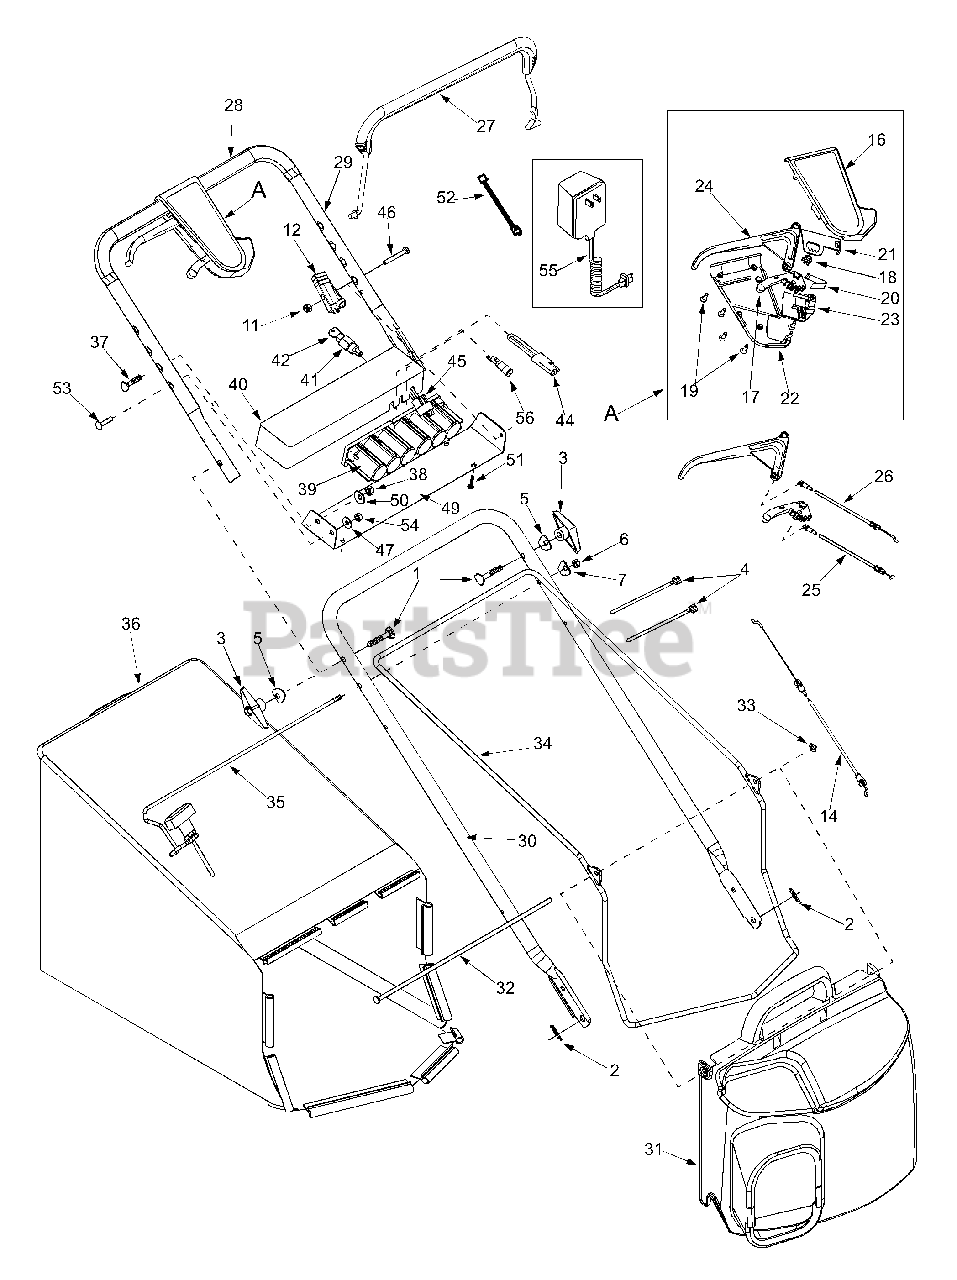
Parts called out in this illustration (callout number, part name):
1	Carriage Bolt 5/16-18 x 2.0
2	Cotter Pin .072 x 1.12 Lg.
3	Knob Assembly 5/16-18
4	Cable Tie
5	Saddle Washer .320 ID x .830 OD
6	Handle Knob 1/4-20
7	Saddle Washer
11	Lock Nut 1/4-20
12	Control Cable Housing
14	Control Cable 44"
16	Upper Control Housing
17	6 Speed Shift Lever
18	Gear Insert
19	C Sunk Tap Screw #10
20	Shift Lever Spring
21	6 Speed Rack Cable Brkt.
22	Lower Control Housing
23	Cable Mounting Cap
24	Control Lever
25	6 Speed Cable
26	Drive Cable 52"
27	Control Handle
28	Foam Grip
31	Grass Bag Cover
32	Pivot Rod
33	Cap Nut
36	Grassbag
37	Carriage Bolt 5/16-18 x 1"
38	Hex Nut 5/16-18
39	Battery Pack
40	Upper Battery Tray
41	Ignition Switch
42	Ignition Key
44	Plug
45	Wire Harness
46	Hex Bolt 1/4-20 x 1.3"
47	Bell Washer 1/4" ID
51	Tap Screw 1"
52	Harness Extension
53	Screw 1/4-20 x 1.25
54	Hex Nut 1/4-20
55	Battery Charger
56	Fuse Holder
